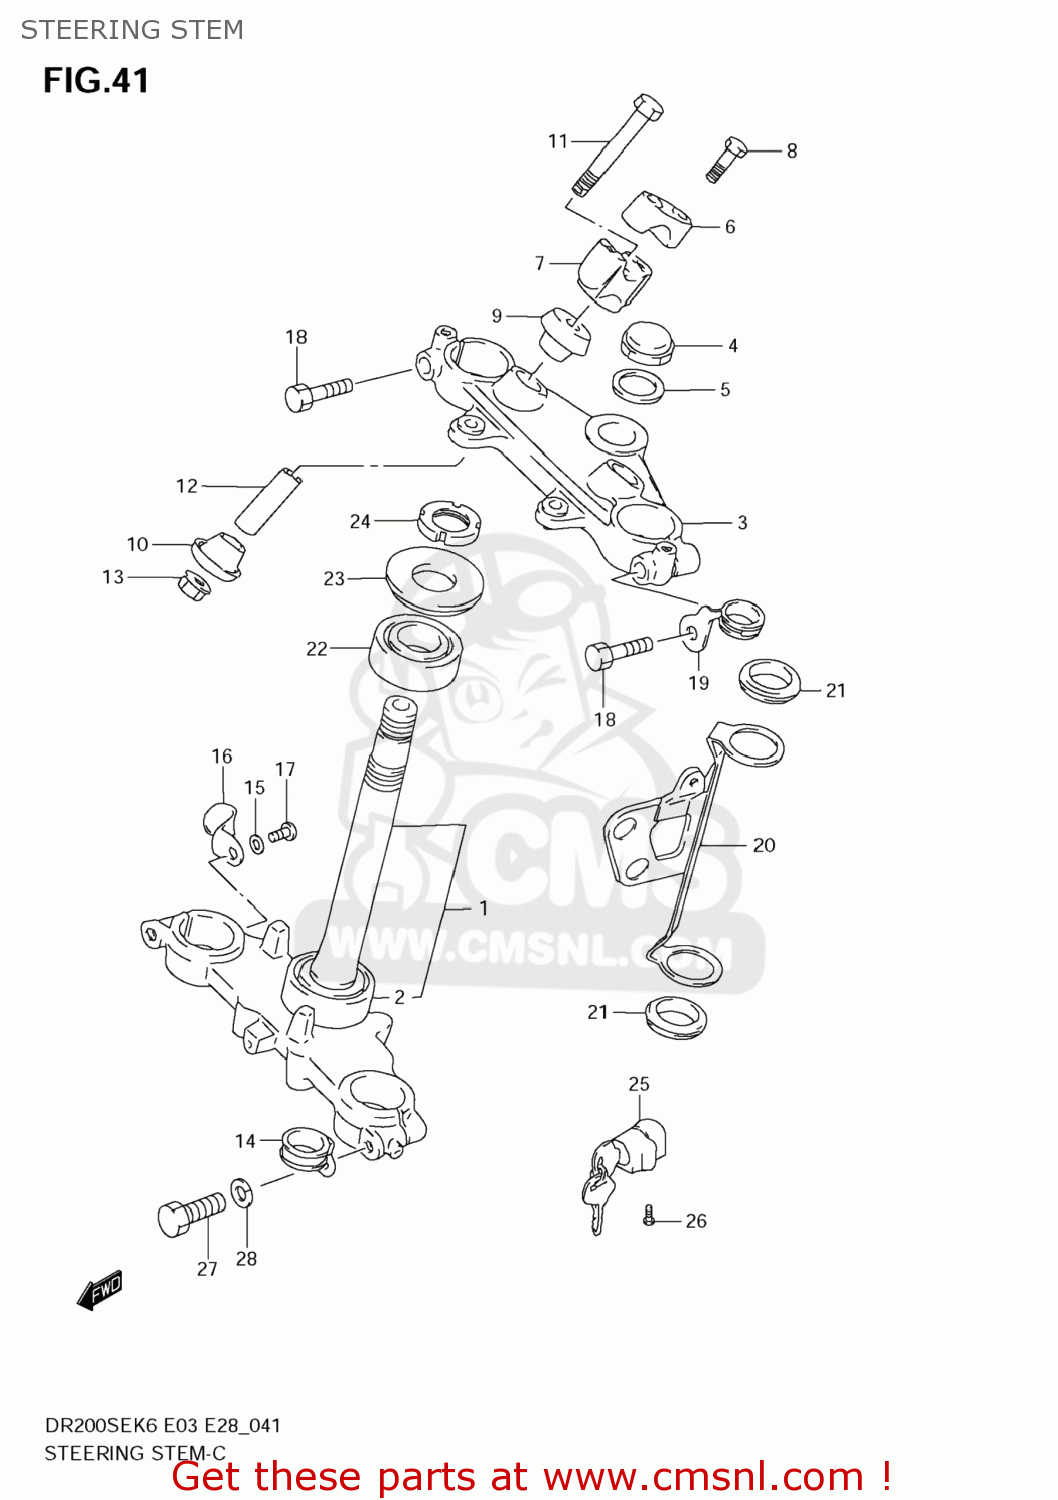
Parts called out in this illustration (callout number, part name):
1	STEM,STEERING
2	BEARING(30X55X17)
3	HEAD,STEERING STEM
4	NUT,CAP
5	WASHER
6	HOLDER,HANDLE UPR
7	HOLDER,HANDLEBAR LWR
8	BOLT
9	RUBBER,HANDLE HOLDER
10	CUSHION,RUBBER UNDER
11	BOLT,HANDLE HOLDER(10X70)
12	SPACER
13	NUT
14	CLIP,LOWER
15	WASHER,LOCK
16	CLIP
17	SCREW
18	BOLT
19	CLIP
20	BRACKET,HEADLAMP,R
21	CUSHION,HEADLAMP HSG BRACKET
22	BEARING(25X47X15)
23	SEAL,STEERING UPR DUST
24	NUT,STEERING
25	LOCK SET,STEERING
26	SCREW
27	BOLT,INNER TUBE FITTING
28	WASHER,LOCK
